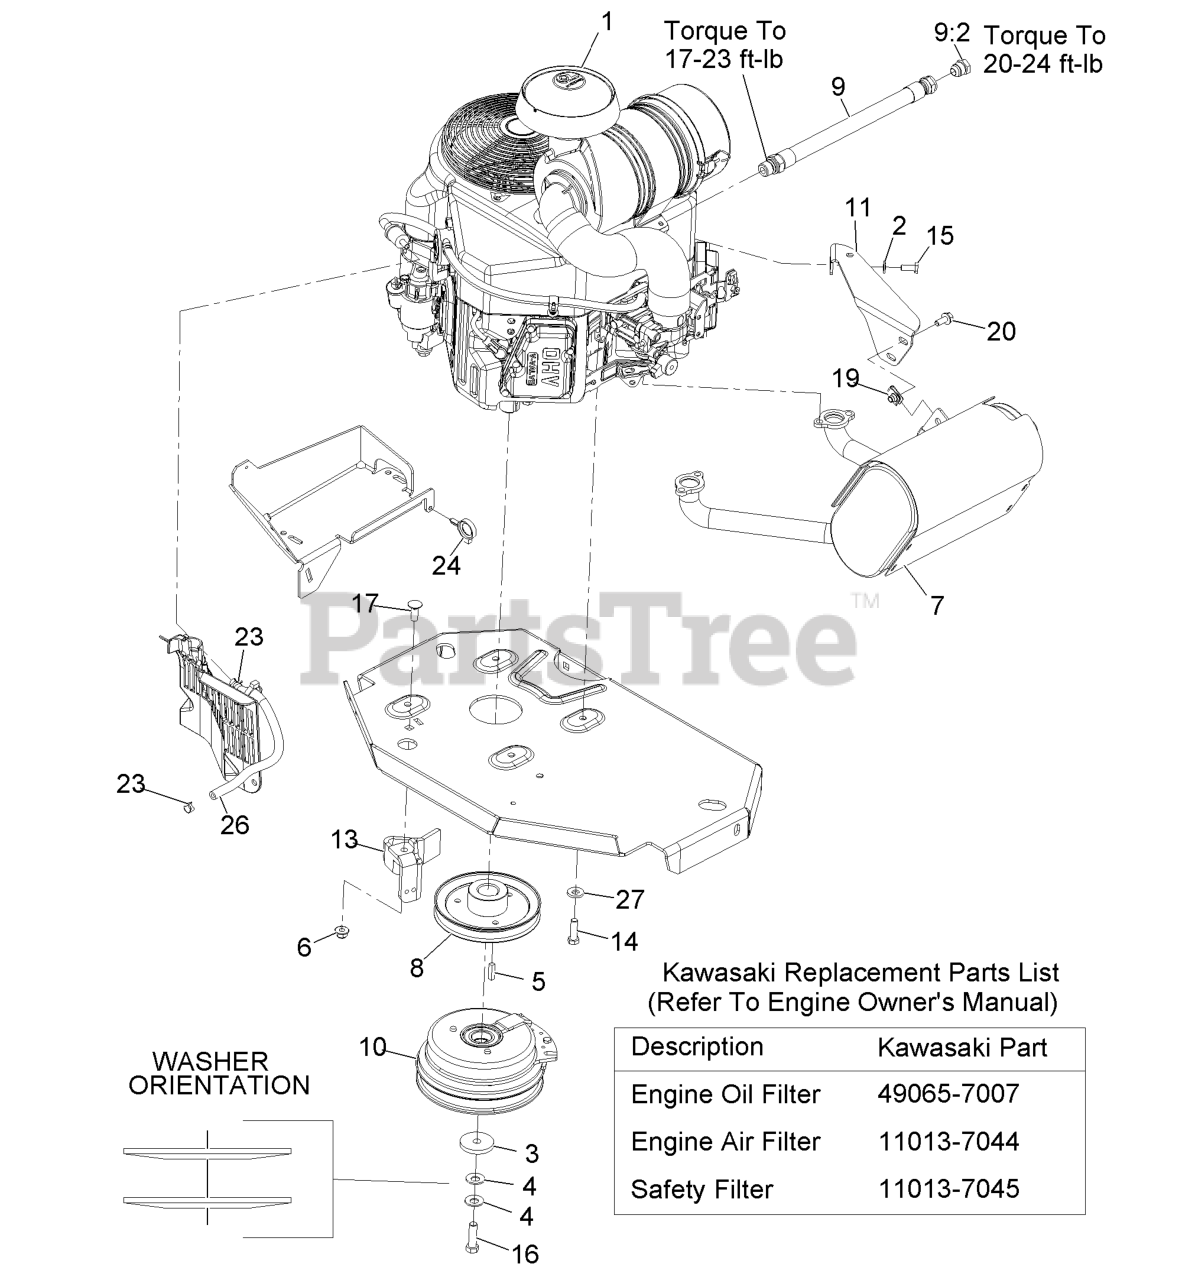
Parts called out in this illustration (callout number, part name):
2	WASHER-SPRING
3	WASHER-CLUTCH
4	WASHER-SPRING
6	NUT-HF, NI
7	MUFFLER
8	SHEAVE
10	CLUTCH KIT
11	BRACKET-MUFFLER
13	CLUTCH-ANCHOR
14	SCREW-HH
15	SCREW-HH
16	SCREW-HH 7/16-20 X 1 1/2 W/LOCTITE
17	SCREW-CARR
20	SCREW-HHF
23	CLAMP-HOSE
24	CLAMP-HOSE
26	HOSE-FUEL
27	WASHER-BELLEVILLE
